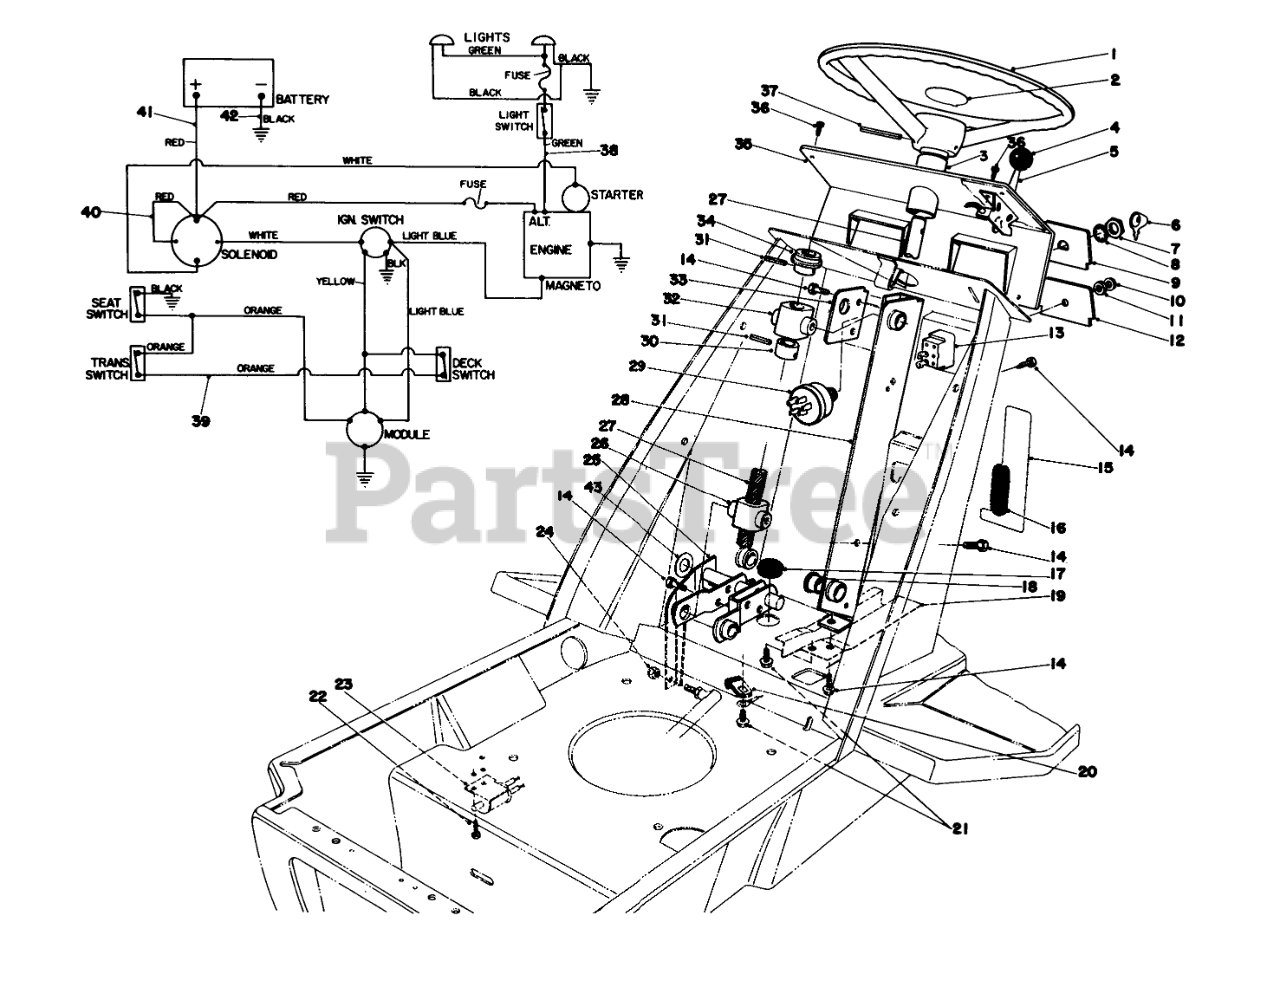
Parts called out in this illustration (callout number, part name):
1	Steering Wheel
2	STEERING WHEEL CAP
3	Tube Steering
4	KNOB-CONTROL
5	Throttle Control (Incl. Ref. #4)
6	Key
7	NUT-HH
8	Lockwasher
9	DASH PANEL INSERT
10	NUT-BULB
11	NUT-LOCK
12	DASH PANEL INSERT
13	Light Switch (Incl. Ref.#10 & 11) (Model #57360)
14	SCREW-HWHTF
15	Decal-Deck
16	Edge Molding
17	GROMMET
18	BEARING-FLANGE
19	WIRE HARNESS SHLD B
20	CLIP-FUEL LINE
21	SCREW-HWH
22	SCREW-TAPTITE
23	DECK INTERLOCK SWITCH
24	Nut
25	STEERING LINK WA BO
26	FOLLOWER STEER SHAFT
27	STRG SHAFT
28	STRG BRKT B
29	Ignition Switch (Incl.Ref. #7 & 8)
30	STRG SHAFT COLLAR
31	PIN-SPRING
32	BRG STEERING SHAFT
33	STRG BRG SUPPORT
34	Collar Steering Shaft
35	DASH PANEL
36	SCREW-HWHTF
37	PIN-ROLL
38	Wire Harness Light
39	WIRE HARNESS
40	SOLENOID WIRE
41	WIRE ASM
42	WIRE ASM
43	WASHER
